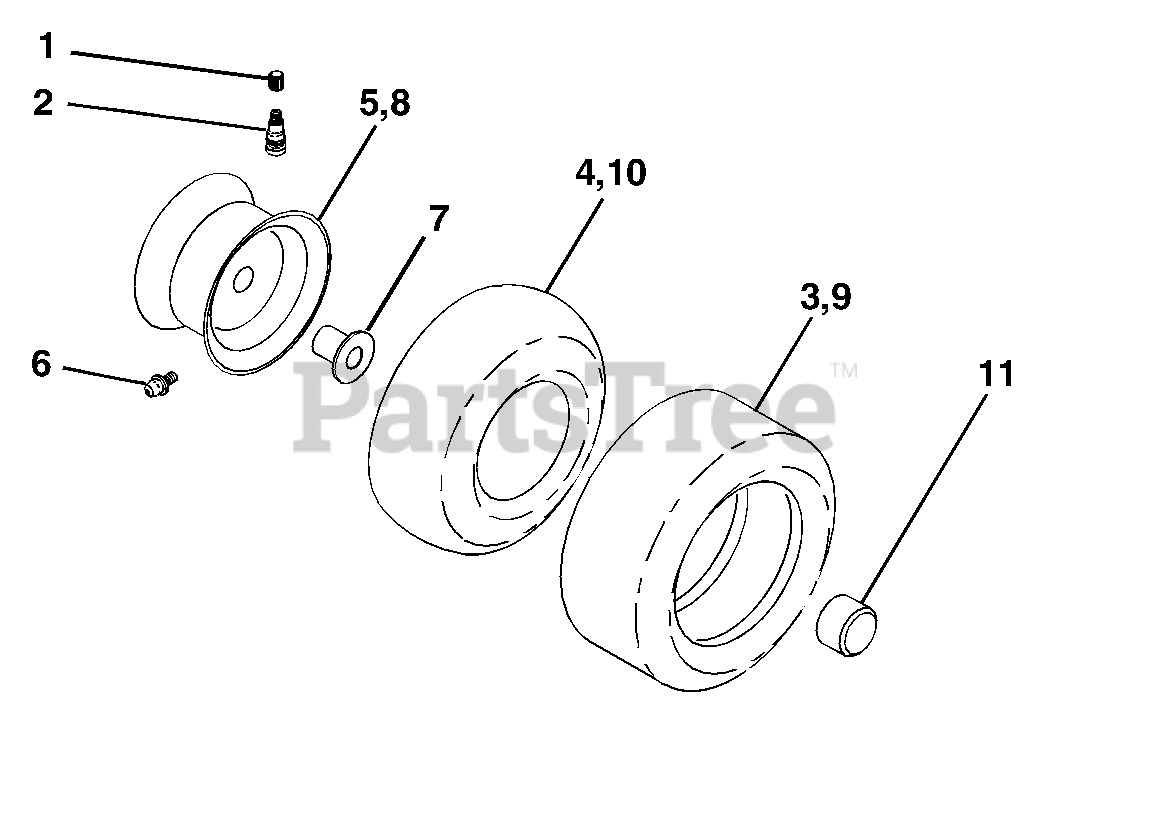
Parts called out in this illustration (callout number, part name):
1	Cap Valve Tire
2	Stem Valve
3	Tire F T 15 x 6 0 - 6 Service
4	Tube Front (Service Item Only)
5	Rim Asm 6"front Service
6	Fitting Grease (Front Wheel Only)
7	Bearing Flange (Front Wheel Only)
8	Rim Asm 8"rear Service
9	Tire R T 20 x 10 -8 C Service
10	Tube Rear (Service Item Only)
11	Cap Axle 1 50 x 1 00
